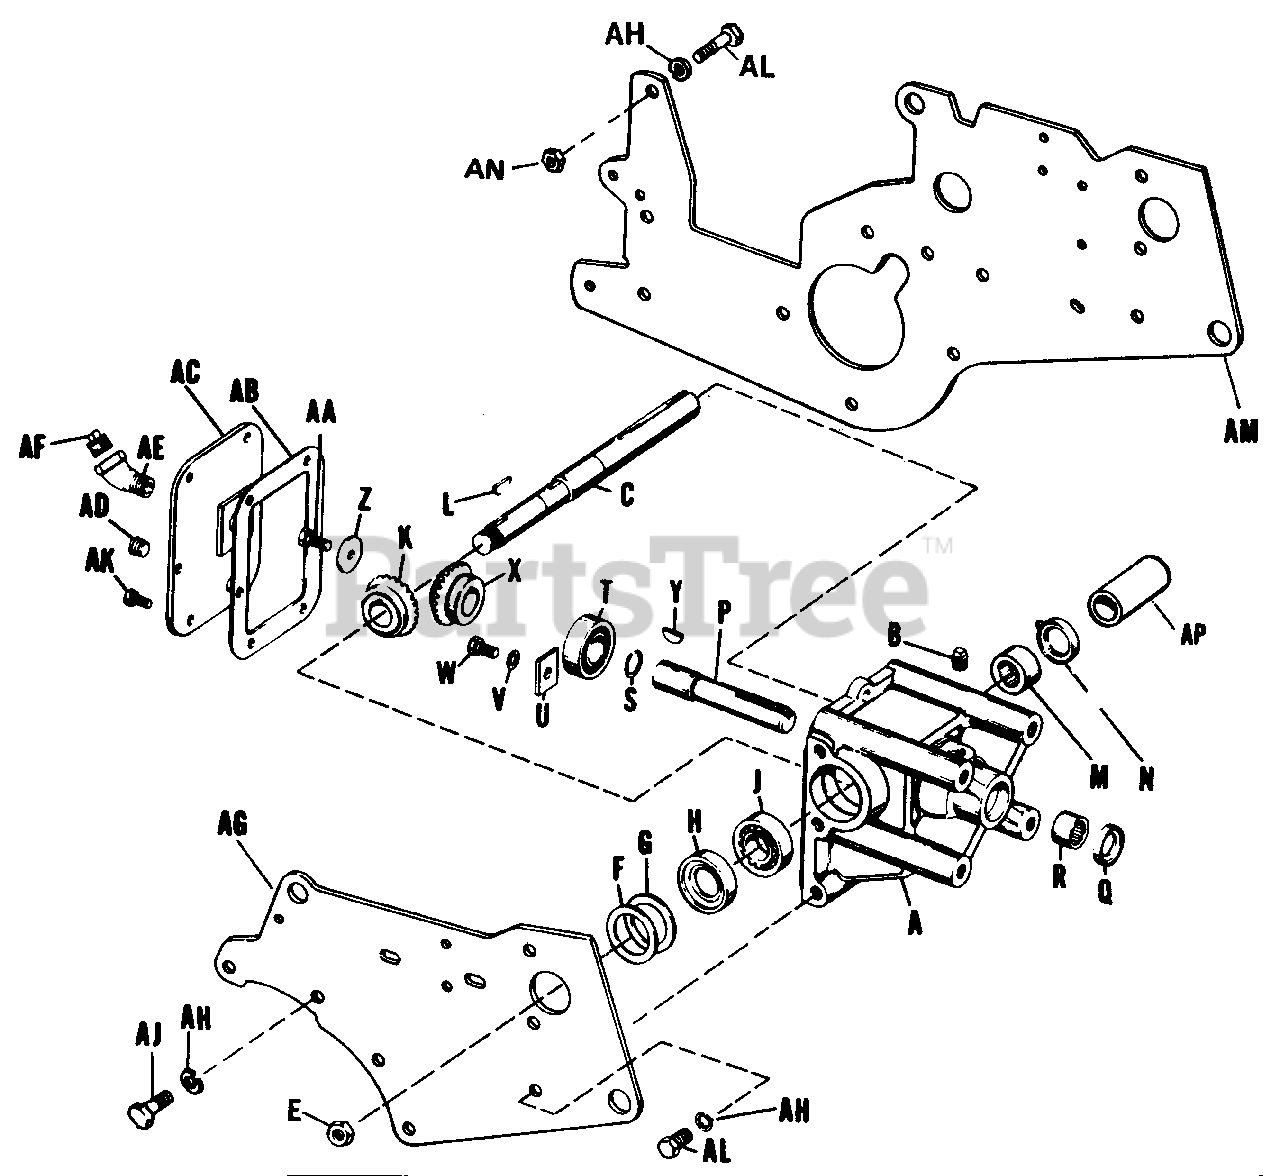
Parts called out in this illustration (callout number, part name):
A	Bevel Gear Housing, W/Bearings
B	Pipe Plug
C	Drive Shaft
E	Hex Jam Nut
F	Shim (As Required)
H	Oil Seal
J	Ball Bearing
K	Bevel Driven Gear
M	Needle Bearing
P	Driven Shaft
Q	Oil Seal
R	Needle Bearing
S	Retaining Ring
T	Ball Bearing
U	Bearing Clamp Plate
V	Lock Washer, 5/16"
W	Hex Capscrew, 5/16"-18 x 5/8" lg.
X	Bevel Driven Gear
AA	Hex Capscrew, 5/16"-18 x 3/4" lg.
AC	Housing Cover Assembly
AD	Pipe Plug
AE	Street Elbow
AF	Pipe Plug
AG	R. H. Side Plate
AH	Lock Washer, 7/16"
AJ	Hex Cap Screw 7/16"-14 x 1" lg.
AK	Hex Cap Screw 1/4"-20 x 5/8" lg.
AL	Hex Capscrew, 7/16"-14 x l-1/4" lg.
AM	L.H. Side Plate
AN	Full Hex Nut, 7/16"-14
